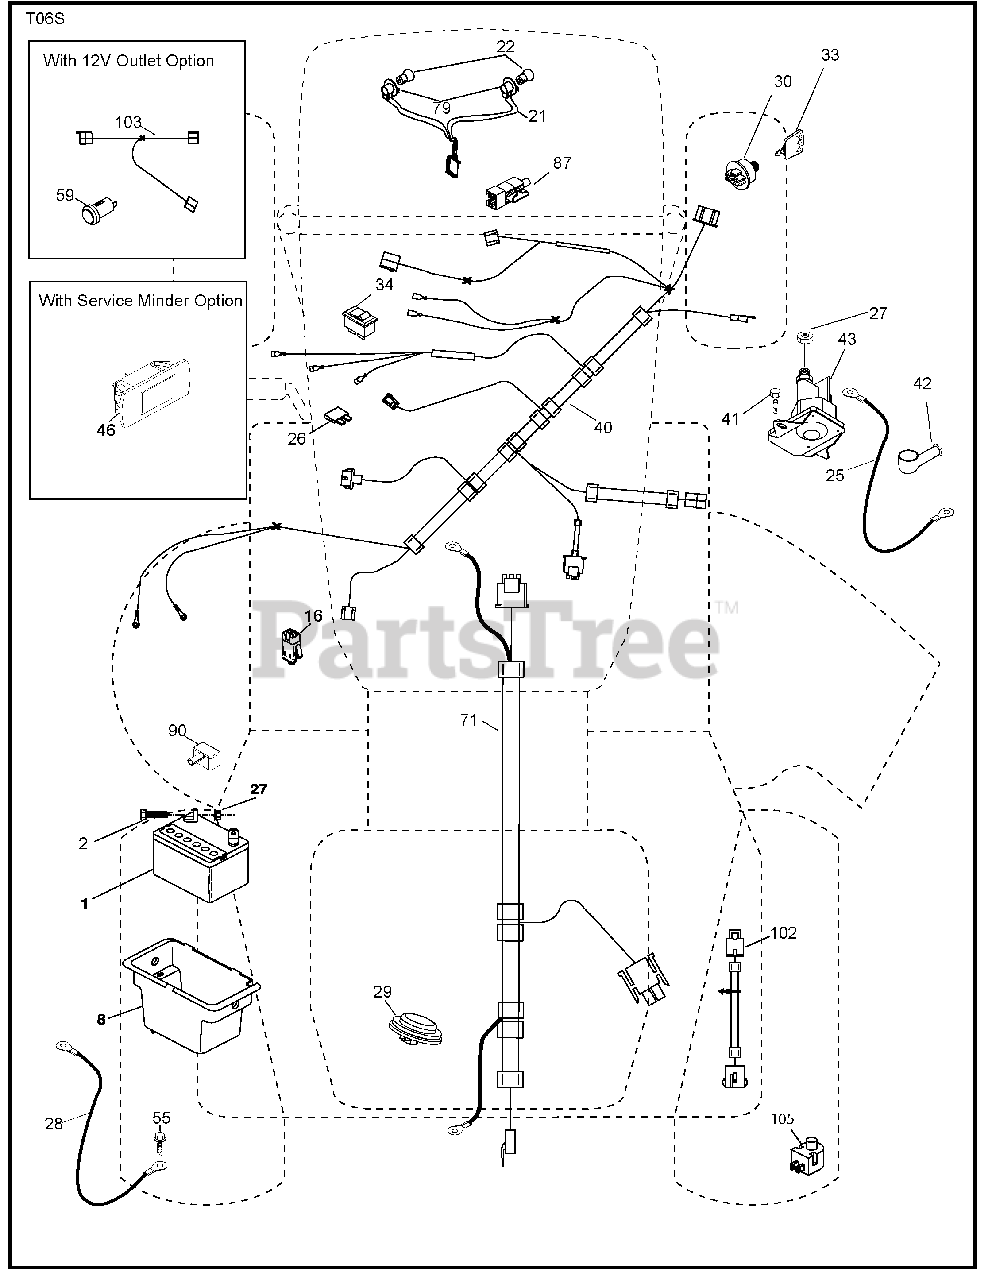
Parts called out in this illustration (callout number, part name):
1	Battery
2	Bolt Hex Head 1/4-20 x 3/4
8	Box Battery
16	Switch Interlock Push-In
21	Harness Socket Light w/4152J
22	Bulb Light
25	Cable Starter
27	Nut Keps Hex 1/4-20 unc
28	Cable, Ground
29	Switch, Seat
30	Switch, Ign
33	Key/Chain
34	Switch Light/Reset
40	Harness Ign. Dash
41	Screw Thd Cut 1/4-20 x 1/2
42	Cover, Terminal
43	Solenoid
46	Gauge Serviceminder Hrmtr
55	Screw Thdrol 5/16-18 x 3/4 TYTT
71	Harness Ign.
79	Socket Asm. Bulb
87	Switch Interlock
90	Cover Terminal
102	Harness Pigtail
105	Switch Reverse
